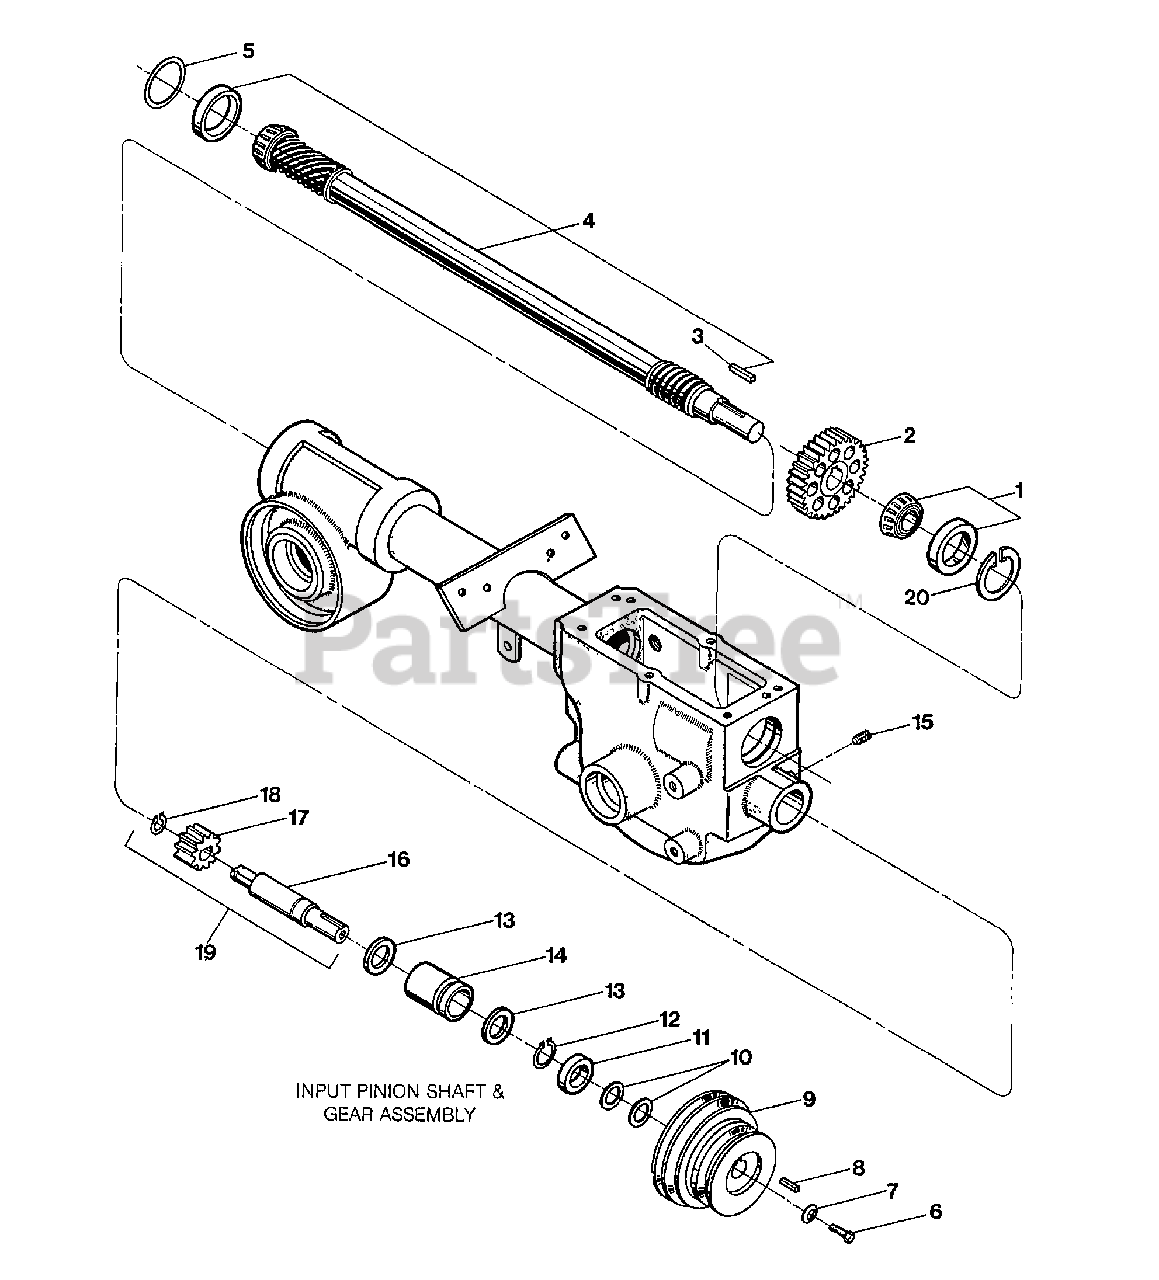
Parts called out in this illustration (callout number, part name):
1	KIT-BRG CONE&RACE-DRIVESHAFT (FRONT OF DRIVE SHAFT)
2	GEAR-SPUR 30 TEETH
3	KEY-.188 SQX1.0
4	KIT-DRIVESHAFT SMFR
4	KIT-DRIVESHAFT
5	SHIM-1.75X1.5X.01
5	SHIM-1.75X1.5X.03
5	SHIM-1.75X1.5X.005
6	SCR-HH 5/16-24X.75 G5 ZP
7	WASHER-.827X.331X.098
8	KEY-.188 SQX1.0
9	PULLEY-TRANS MACH, 3 GROOVES (TWO FOR FORWARD SPEEDS; ONE FOR REVERSE SPEEDS)
10	WASHER # .875 X .65 X .06
11	SEAL-PINION SHAFT PT/85030/00
12	RING-RETAIN EXT .707 ID (SNAP-IN)
13	WASHER-1.022X.752X .059
14	BUSHING-1.24X.75X1.8 GRVD
15	SCR-SS 5/16-18X.375
16	SHAFT-PINION(P-V)
17	GEAR-PINION P/M
18	RING-BOWED EXT .461 ID
19	PINION W/GEAR&SNAP RING (INCL. ONE EACH OF 16-18)
20	RING-RETAINING 5000-181
